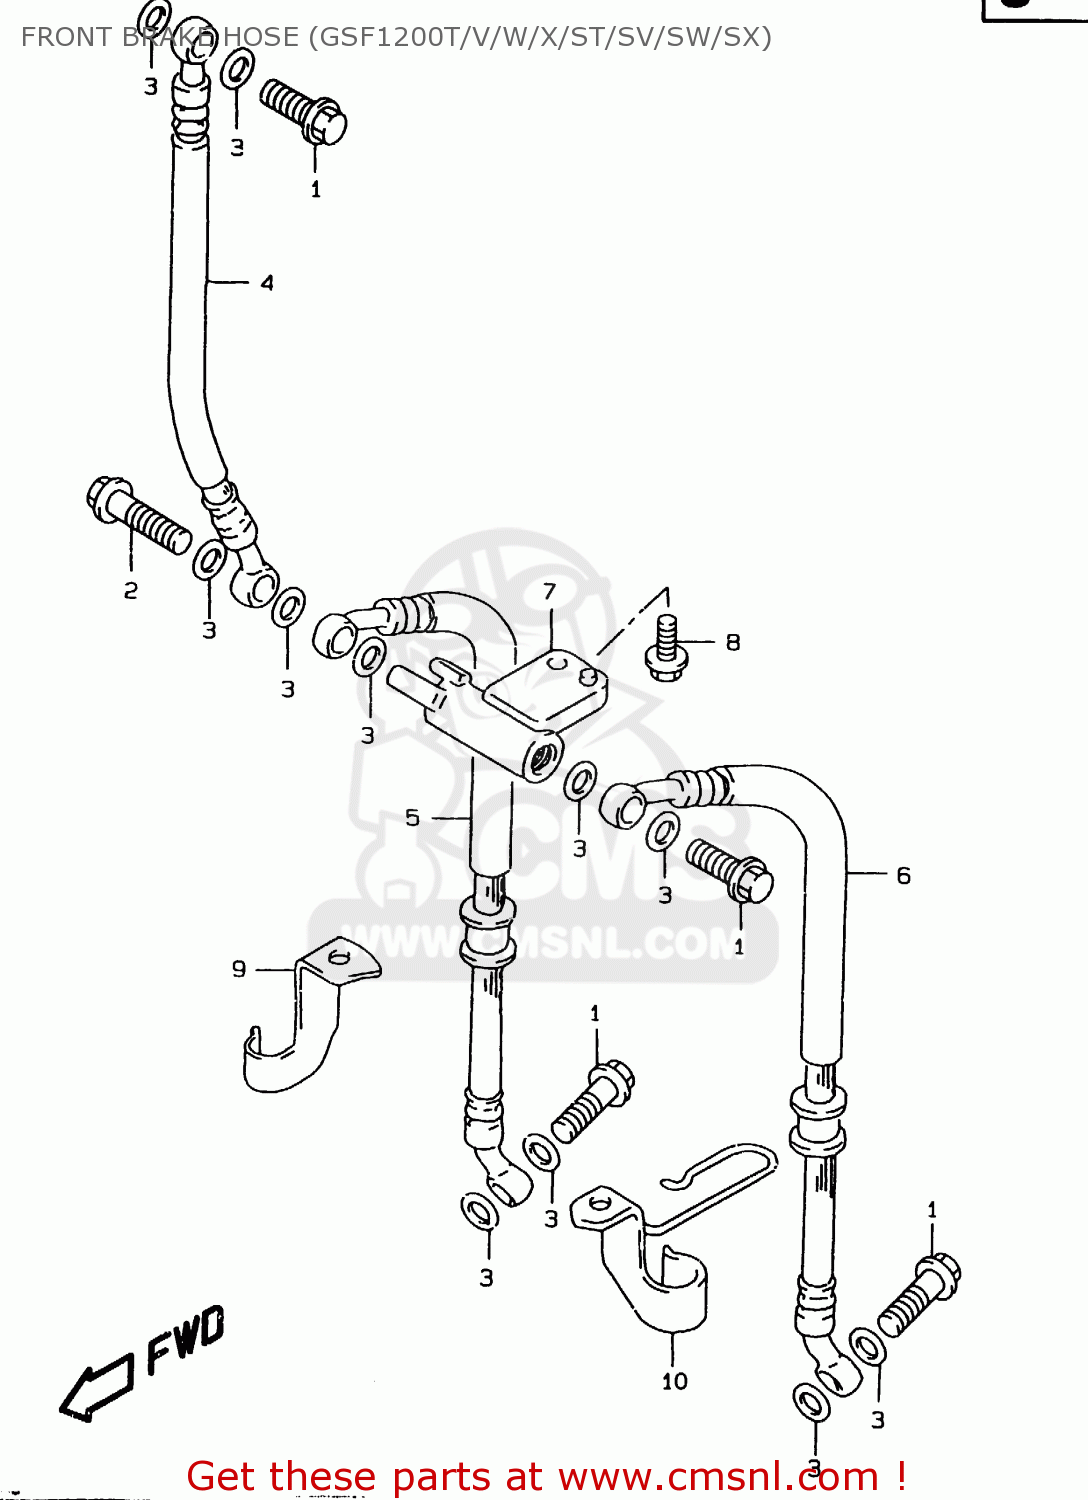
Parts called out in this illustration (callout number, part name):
1	BOLT UNION
2	BOLT UNION
3	WASHER(10X15X1.5)
4	HOSE,FR BRAKE NO.1
5	HOSE,FR BRAKE NO.2,R
6	HOSE COMP,FRONT BRAKE
7	JOINT,BRAKE HOSE
8	BOLT
9	CLAMP,FR BRAKE HOSE,R
10	CLAMP,FR BRAKE HOSE,L
